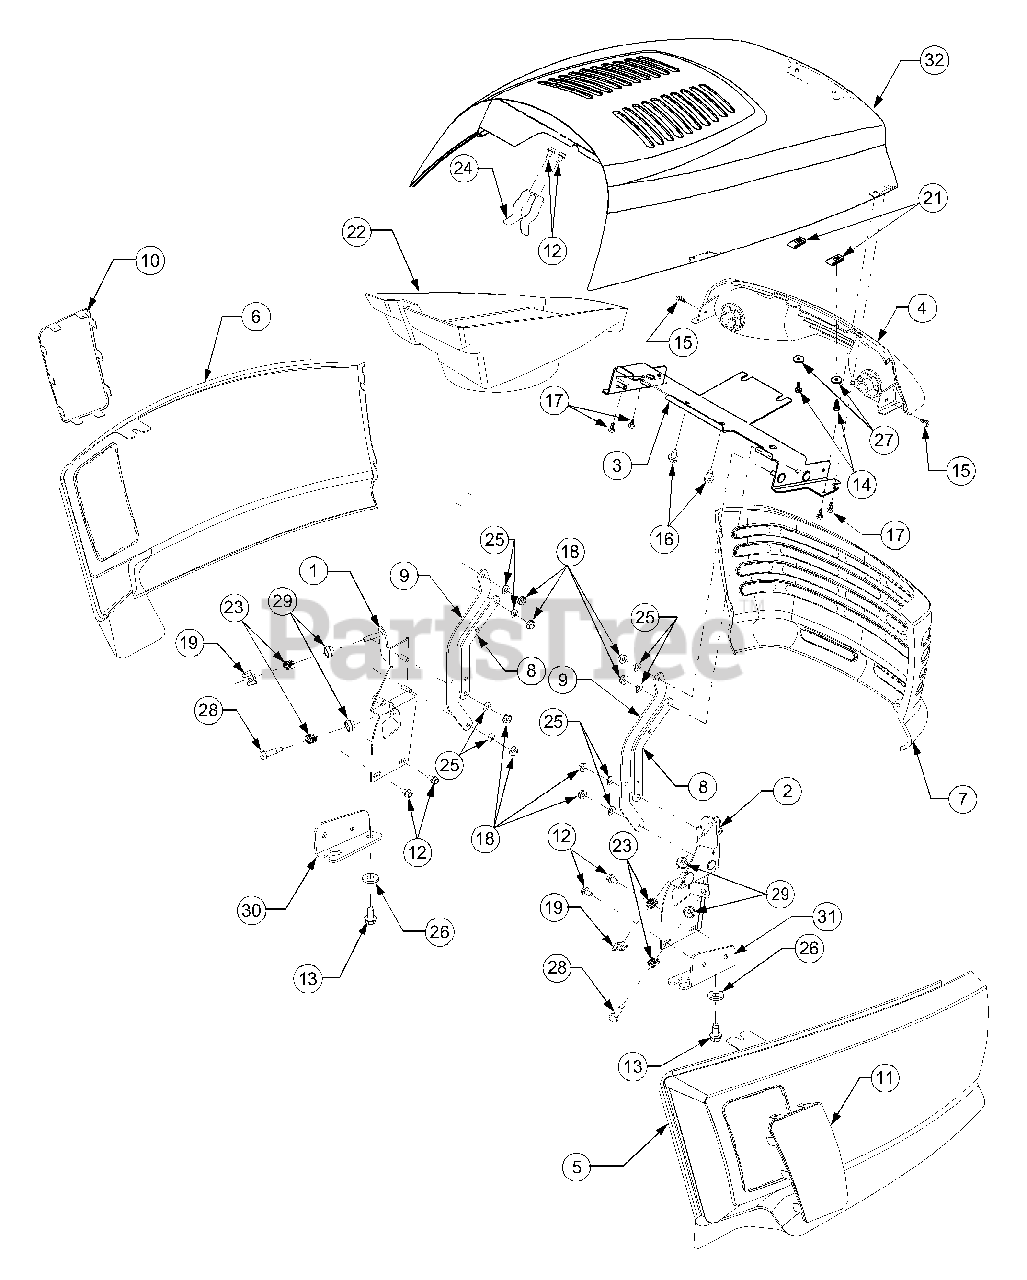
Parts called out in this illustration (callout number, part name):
1	Bracket Assembly, Grille LH
2	Bracket Assembly, Grille RH
9	Link, Hood, Rear
13	Screw, Hx Wash. Hd Tapp, 5/16-18 x .75
14	Screw, Hx Tapp, 10-16 x .625
15	Screw, Hx Wash. Hd Tapp, 10-16 x .5
16	Screw, Hx Wash. Hd Tapp, 5/16-12 x .75
17	Screw, Truss Phillips Tapp, 10-16 x .5
18	Nut, Flange Lock, 1/4-20
19	Nut, Wing, 1/4-20
21	Nut, Speed, 10z U-type
22	Plenum, Hood
23	Spring, Compression, .50 OD x .5 Lg
24	Spring, Latch, Hood
25	Washer, Spring, .265 x.562 x.025
26	Washer, Flat, .385 x 1.0 x .135
27	Washer, Flat, .194 x .62 OD x .063
28	Screw, Shoulder, .31x .75, 1/4-20
29	Bushing, Tapered, .32 ID x .69 OD
